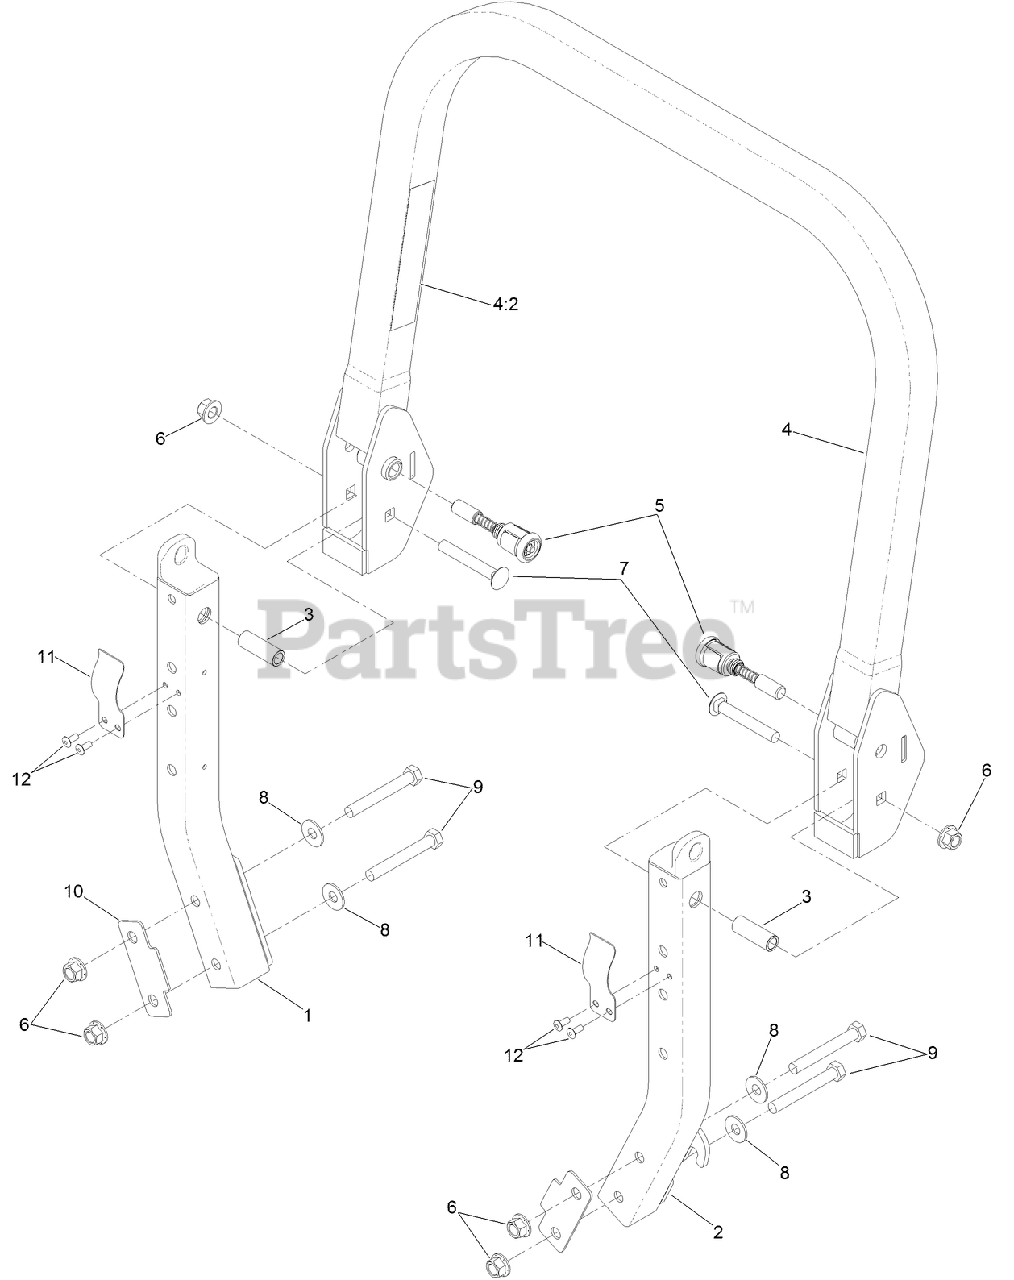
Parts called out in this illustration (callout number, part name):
1	LOWER-ROPS, RH
2	LOWER-ROPS, LH
3	SPACER
4	ROPS UPPER ASM
4:2	DECAL-WARNING
5	PIN-SPRING
6	NUT-LOCK
7	SCREW-CARR
8	WASHER-SPRING
9	SCREW-HH
10	SPACER
11	SPRING-LEAF
12	RIVET-BLIND
